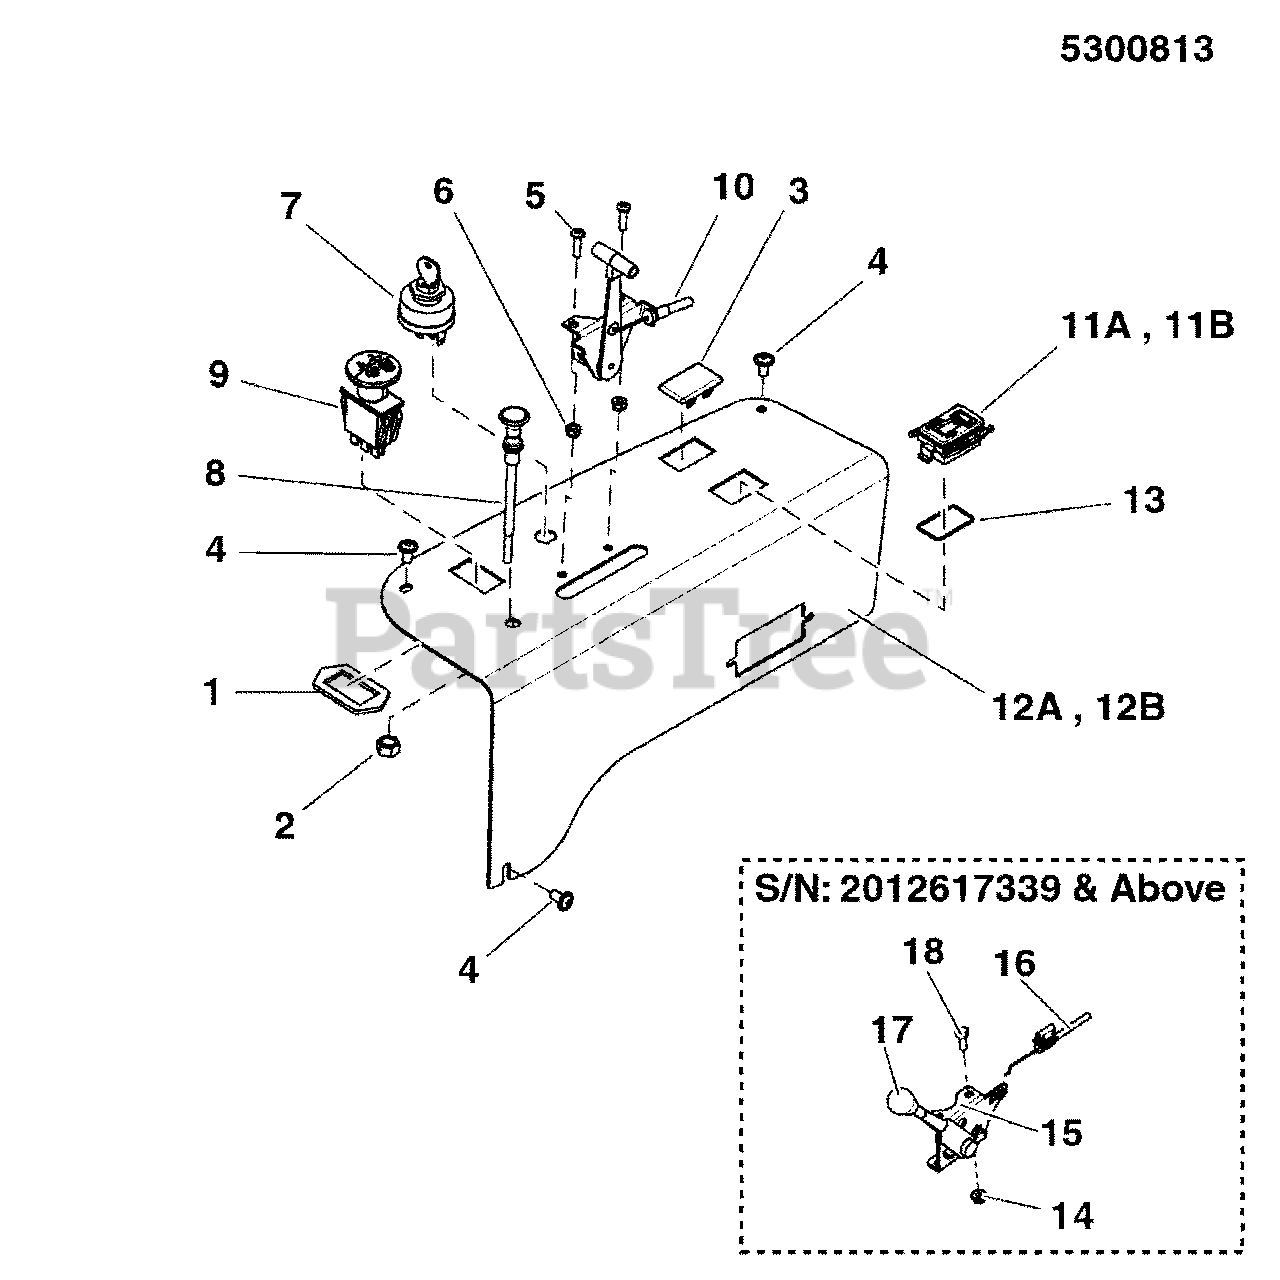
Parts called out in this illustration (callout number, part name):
1	RING, SWITCH RETAINER
2	NUT, 3/8-24 Hex Jam
3	PLUG, .820X1.44 HOLE, BLACK PLASTIC
4	SCREW, ALLEN HEAD 1/4-20X.500 ZINC PHOS
5	HHCS, 1/4-20 X 0.625, GR5, ZINC/CLEAR
6	NUT, 1/4-20 HEX NYLON LOCK
7	SWITCH, IGNITION, 6 POST
8	CABLE, CHOKE CONTROL, 51" (Z)
9	SWITCH, BLADE ENGAGEMENT
10	CABLE, THROTTLE CONTROL, 45"
13	O-RING, 7/8" ID X 1/16" W
14	NUT, Hex, Nylon Lock, #10-24
15	LEVER, THROTTLE CONTROL, HEAVY-DUTY
16	CABLE, THROTTLE, 42"
17	THROTTLE CONTROL HANDLE/KNOB
18	SCREW, #10-24 X 3/4" ROUND PHILLIPS
